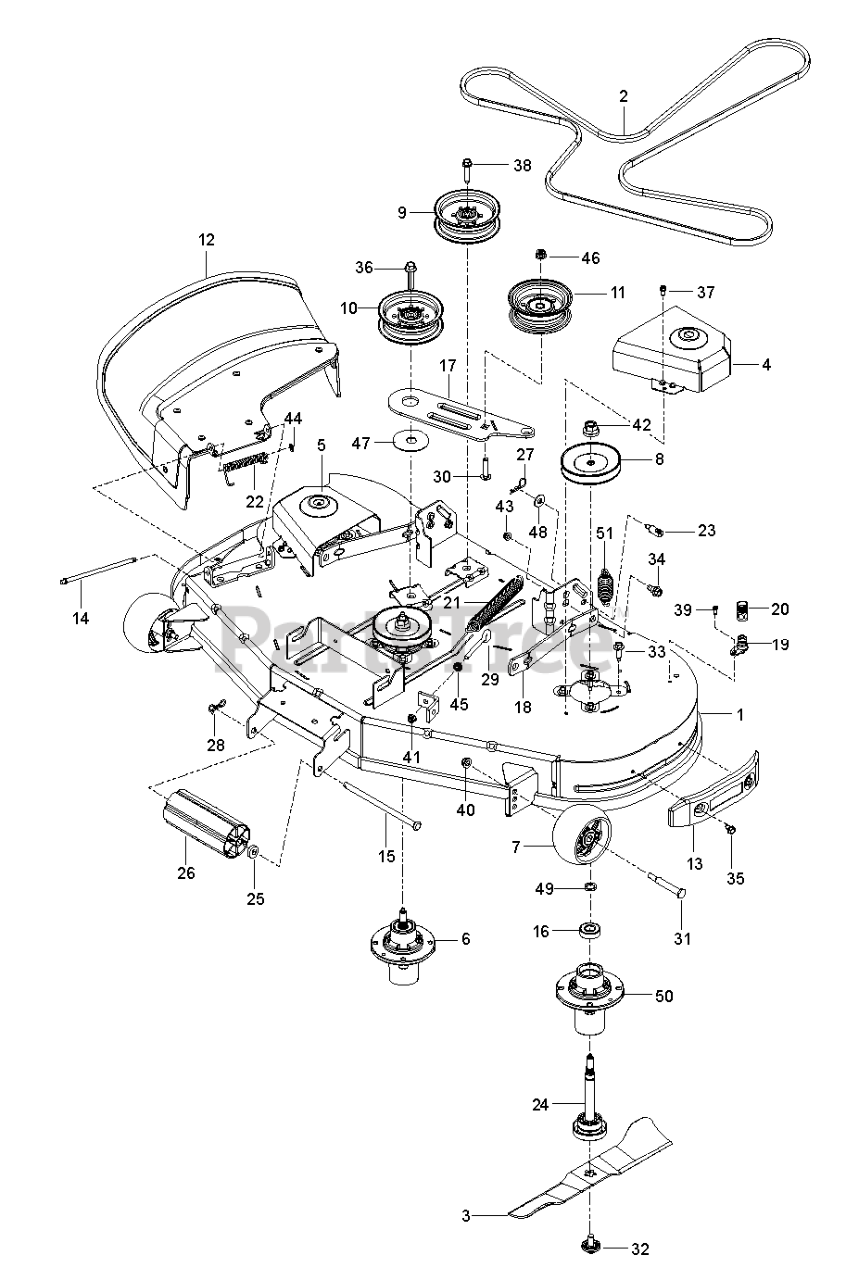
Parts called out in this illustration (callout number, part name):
1	DECK SVC.48.CC.RZ 668
3	BLADE.BAGGER.RES.CLRCT.48".BLK
4	COVER.PNT.MANDREL.LH.ZTR.GREY
5	COVER.PNT.MANDREL.RH.GREY
6	MANDREL ASM, CAST IRON
7	WHEEL.GAUGE.RALLY
8	MANDREL.PULLEY.38.BRIGHT.ZINC
9	PULLEY.IDLER.2006
10	PULLEY.IDLER.MWR.STATI.LH
11	PULLEY.IDLER.48"PRIMARY
12	DEFLECTOR.ASM.48".CLRCT.RES.OR
13	BUMPER 48 CLEARCUT TRIM SIDE A
14	ROD.HINGE
15	ROD.ROLLER.NOSE.NARROW.48"
17	ARM.PNT.CLUTCHING.EDIP
18	ARM.RFIXED.MOWER.SUSPNSIONX431
19	PORT.WASHOUT
20	COUPLING.QUICK CONNECT
21	SPRING.EXTENSION
22	SPRING.42.FCS.DEFLECTOR
23	STUD.FASTNER.W/ANTI-ROTATE
24	SHAFT ASM MANDREL
25	BUSHING.NOSE.ROLLER
26	NOSE ROLLER 48"
27	PIN.COTTER.7/16.BOW TI.
28	PIN.COTTER.5/16.BOW TI
29	EYE BOLT 5/16 X 3.50
31	BOLT.SHOULDER.3/8-16X3-5/8.
32	BOLT.WASHER.ASM.7/16-2
33	BOLT.HEX.WASHR.HED.313-18X1.19
34	BOLT.SHOULDER
35	SHOULDER BOLT 5/16-18TT
36	SCREW.7/16-14 X 2.125.WASHER
37	SCREW.1/4-20X5/8
38	SCREW LT
39	SCR 1/4-20X5/8 HEX SELF TAP ZD
40	NUT 3/8-16 HEX FLG NYLOC ZD
41	5/16-18 NYLOC FLANGE NUT
42	NUT.FLANGE.LOCK.TOP
43	NUT LOCK HEX FLANGE 5/16-18
44	NUT PUSH M
45	NUT 5/16C WHIZ
48	WASHER
49	WASHER.SPACER.MANDREL
50	MANDREL, HOUSING - CAST IRON
